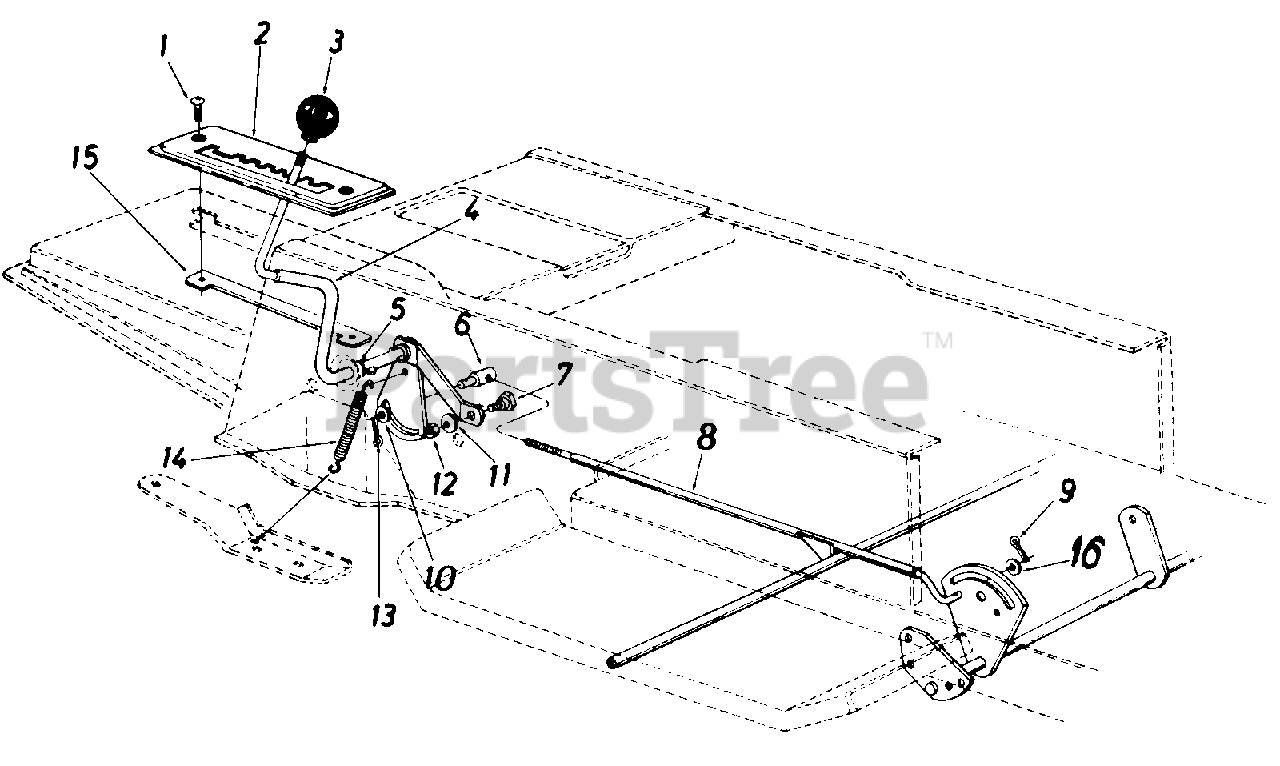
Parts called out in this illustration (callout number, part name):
1	Truss Mach. Scr. 1/4-20 x .75" Lg.
2	Speed Selector Plate 4-Speed
4	Speed Selector Cam Ass'y.
5	Flat Washer .53" I.D. x .93" O.D.
6	Ferrule 3/8-24 x .37" Dia.
7	Shld. Bolt .435" Dia. x .160
8	Speed Control Rod Ass'y.
9	Cotter Pin 3132" Dia. x .75" Lg.
10	Fl.-Wash..39" I.D.
11	L-Wash. 5/16" I.D.*
12	Hex Nut 5/16-18 Thd.
13	Hairpin Cotter 1/8" Dia.
14	Spring
15	Clamping Plate
16	Fl-Wash. .47" I.D. x .88" O.D. x .063
